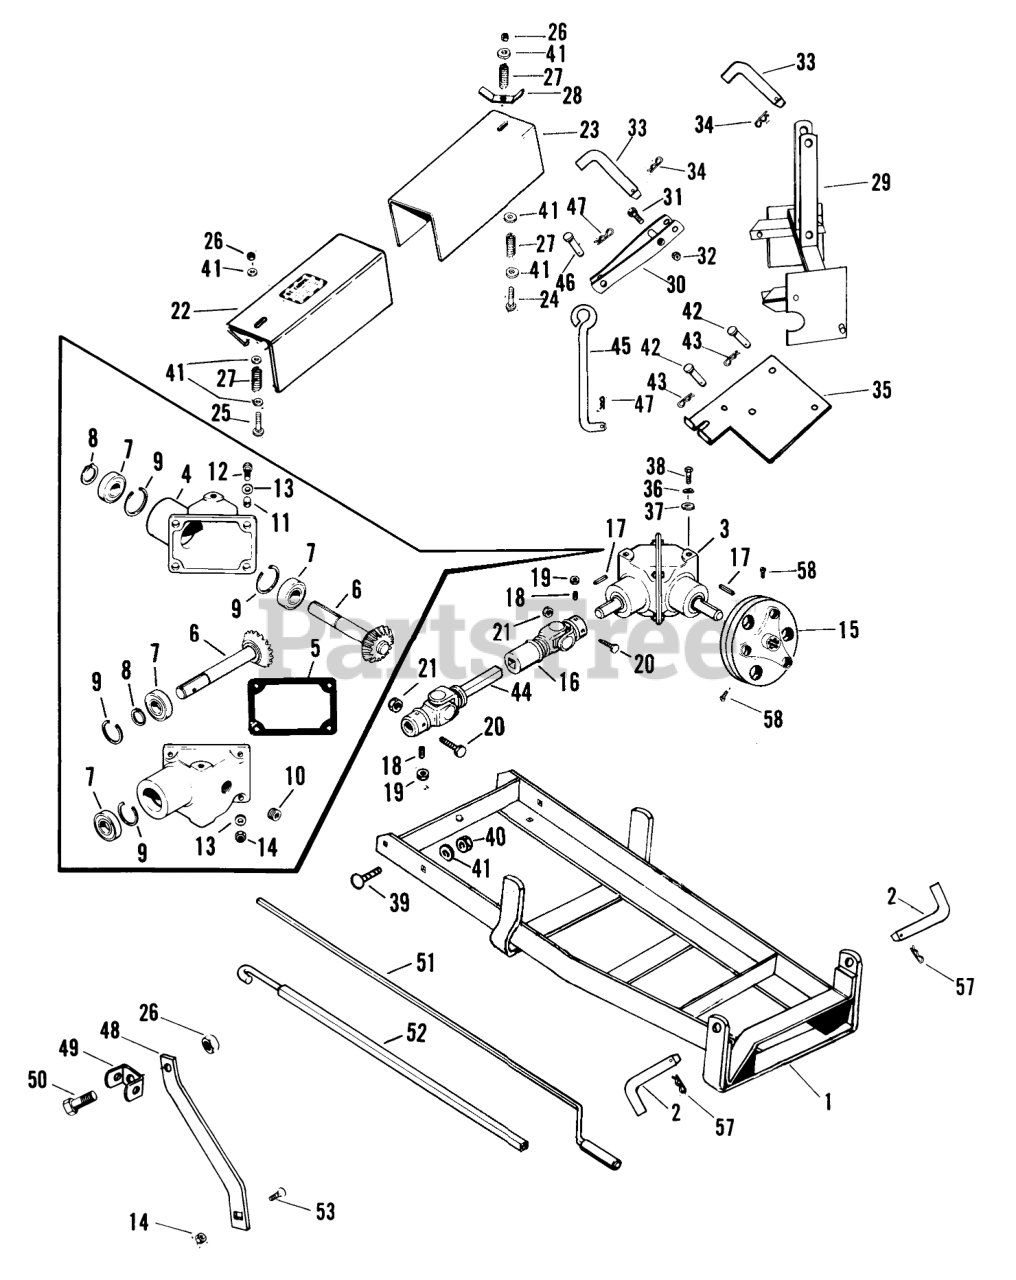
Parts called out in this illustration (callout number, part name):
1	Mounting Frame
2	Pin
3	Assembly-Gearbox
4	Gearbox Case Half
5	Gasket
6	Assembly-Shaft & Gear
7	BEARING-GEAR BOX
8	RING-SNAP
9	Ring-Snap
10	PLUG PIPE
11	BUSHING
12	Bolt
14	Keps Nut 5/16-18
15	Flex Coupling
16	Slip Assembly-Female End
18	Set Screw 3/8-16 x 5/8
19	Nut
20	HEX HD CAP SCREW -4
20	Bolt
22	PTO Cover (Top)
23	PTO Cover (Bottom)
24	Bolt
25	Bolt-3/8-16 x 1 1/4
26	Nut
27	SPRING
28	Wing Bracket
29	Gearbox MountingBracket
30	Bell Crank Assembly
31	Bolt 1/2-13 x 3 1/2
32	Eslok Nut
35	Gearbox Mounting Plate
36	LOCKWASHER
37	WASHER
38	BOLT
39	Bolt
41	Washer
43	Pin
44	Slip Assy.-Male End
45	Pin
46	Lock Nut 5/16-18
48	Crank Rod Support
49	Crank Rod Guide
50	Bolt
51	Crank Rod
52	Crank Rod Extension
53	Carriage Bolt 5/16-18 x 3/4
54	Decal
55	Decal
58	Set Screw
